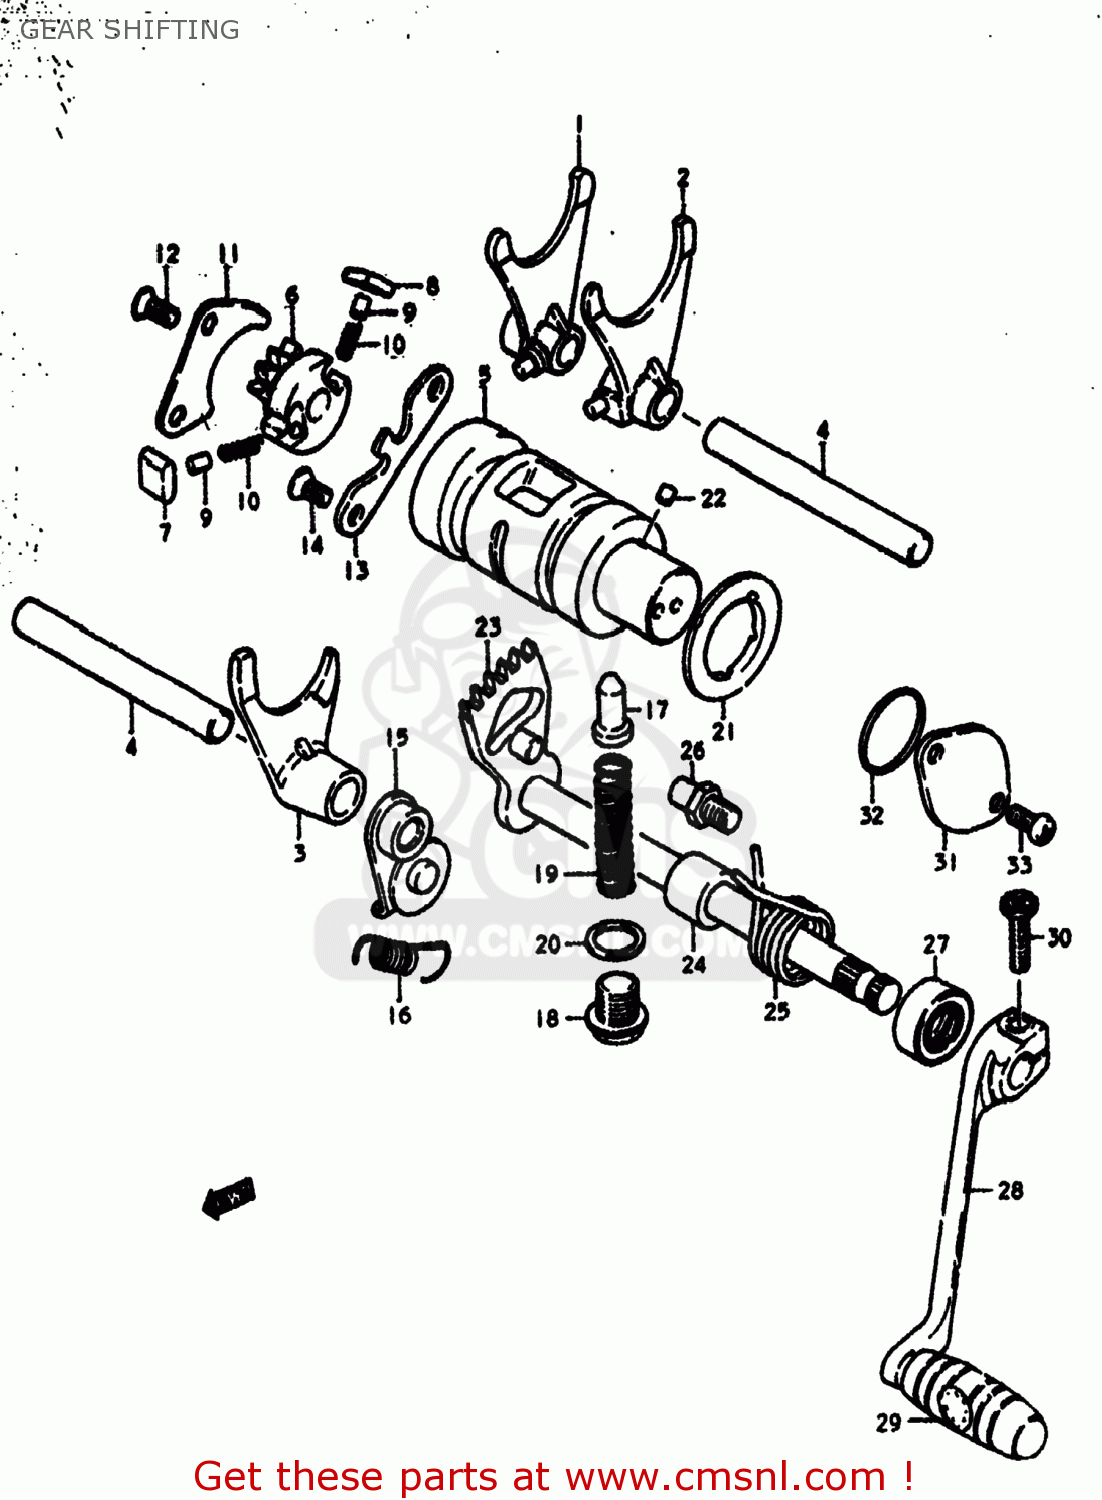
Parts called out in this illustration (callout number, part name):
1	FORK,GEAR SHIFT NO.1
2	FORK,GEAR SHIFT NO.2
3	FORK,GEAR SHIFT NO.3
4	SHAFT,GEAR SHIFT FORK
5	CAM,GEAR SHIFT
6	RETAINER,GEAR SHIFT CAM
7	PAWL,GEAR SHIFT NO.1
8	PAWL,GEAR SHIFT NO.2
9	PIN(5X8)
10	SPRING
11	LIFTER,GEAR SHIFT PAWL
12	SCREW
13	GUIDE,GEAR SHIFT CAM
14	SCREW
15	STOPPER,GEAR SHIFT CAM
16	SPRING
17	STOPPER,GEAR SHIFT CAM NO.2
18	PLUG
19	SPRING
20	GASKET(14X19.2X2) (NAS)
21	PLATE,GEAR SHIFT CAM STOPPER
22	PIN 4X6
23	SHAFT,GEAR SHIFT
24	SPACER(12X20X15.3)
25	SPRING
26	STOPPER,GEAR SHIFT CAM
27	OIL SEAL
28	LEVER ASSEMBLY,GEAR SHIFTING
29	RUBBER,GEAR SHIFT PEDAL
30	BOLT
31	CAP,GEAR SHIFT CAM PIVOT
32	O-RING (D:2.4 ID:26.2)
33	SCREW
